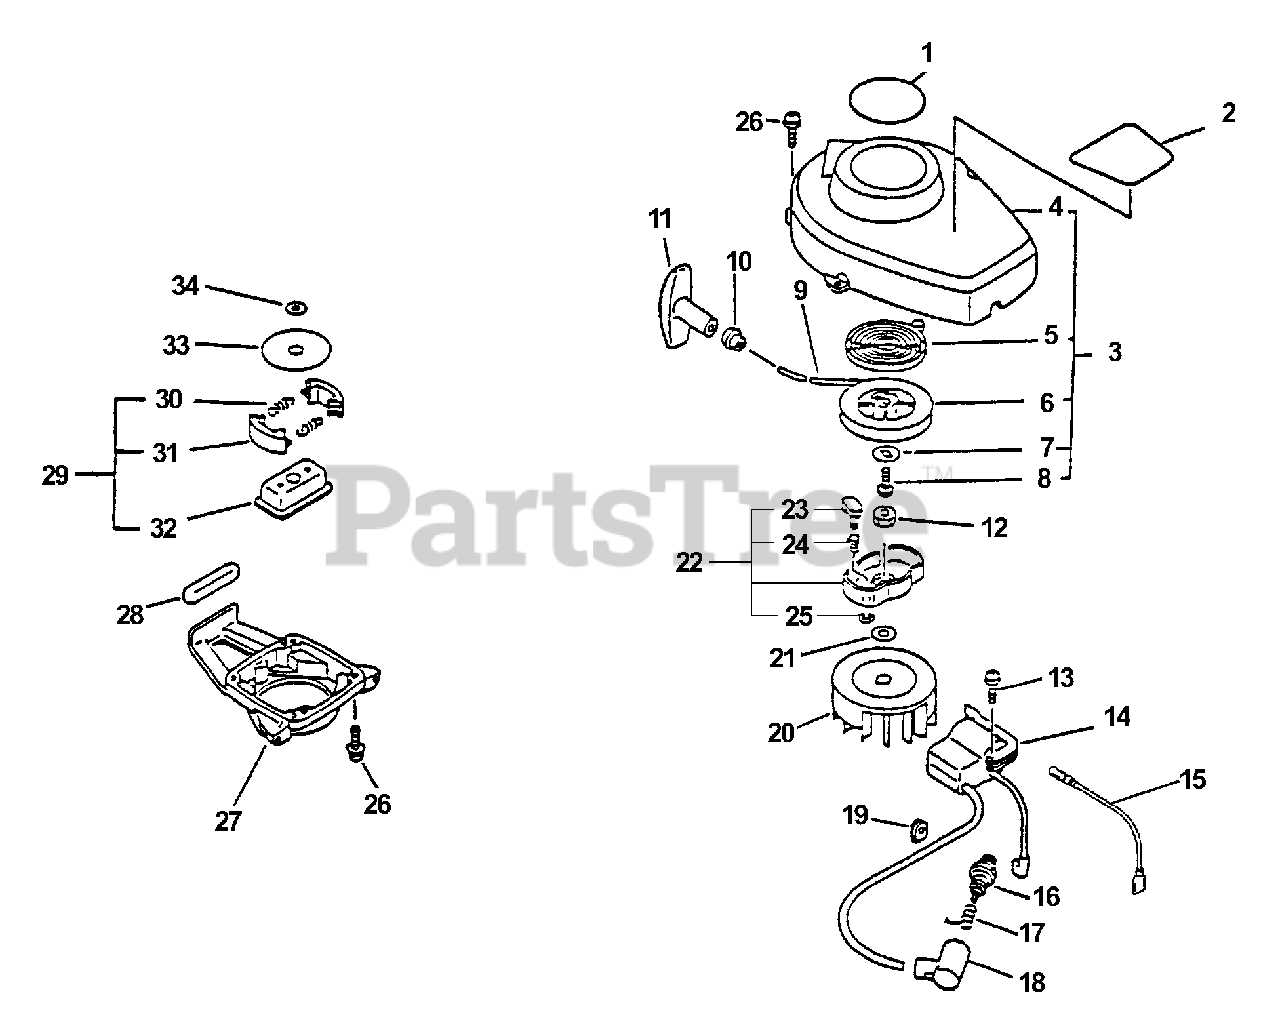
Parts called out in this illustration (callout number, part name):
1	LABEL - MODEL HC-2000
2	LABEL - CAUTION
3	STARTER ASSY
4	CASE, STARTER
5	SPRING, REWIND
6	REEL, ROPE
7	WASHER
9	ROPE, STARTER - 3.5X1000
10	GUIDE, ROPE
11	GRIP, STARTER
12	NUT - LEFT HAND
13	SCREW - 4X22
14	COIL, IGNITION
15	LEAD - IGNITION
16	SPARK PLUG -- BPM-7A
16	SPARK PLUG -- BPM-7Y
16	SPARK PLUG -- RCJ-7Y
17	TERMINAL, SPARK PLUG CAP
18	CAP, SPARK PLUG
20	FLYWHEEL
21	WASHER - 8
22	STARTER PAWL ASSY
23	PAWL, STARTER
24	SPRING, RETURN
25	RING, RETAINING - 4
26	SCREW - 4X16
27	CASE, CLUTCH
28	CUSHION, FUEL TANK
29	CLUTCH ASSY
30	SPRING, CLUTCH
31	SHOE, CLUTCH
32	HUB, CLUTCH
33	PLATE, CLUTCH
34	WASHER, CLUTCH
